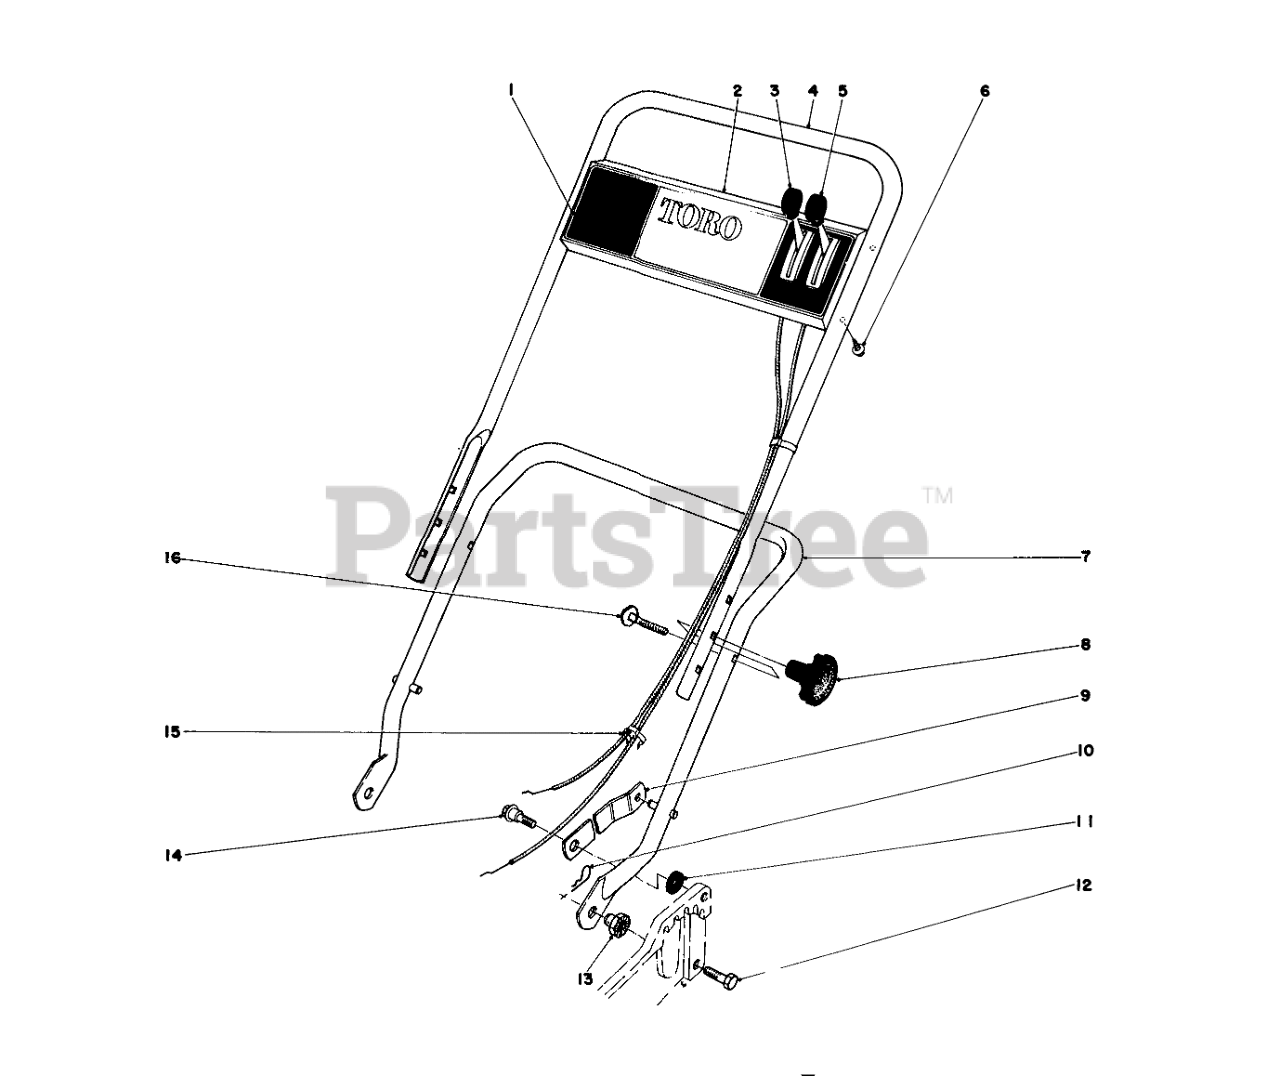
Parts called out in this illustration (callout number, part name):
1	Decal Control Plate
2	Control Plate
3	Throttle Control
4	Upper Handle
5	Traction Control
6	Screw
7	Lower Handle
9	HANDLE LATCH
10	PIN-COTTER, HAIR
11	SPACER
12	SCREW-HH
13	HANDLE PIVOT NUT
14	SCREW-SHOULDER
15	BOWDEN CLIP
16	HANDLE SCREW
